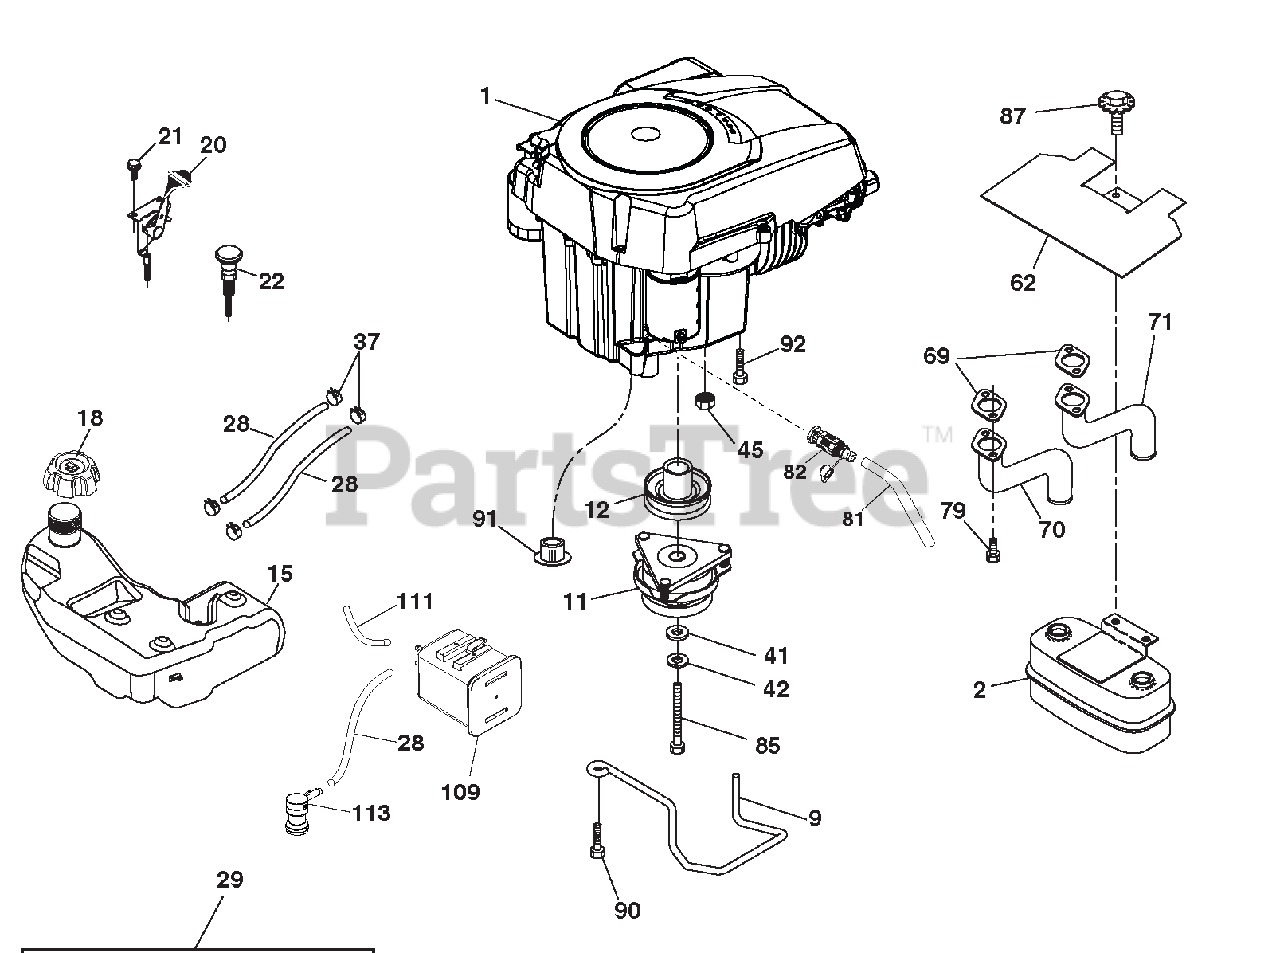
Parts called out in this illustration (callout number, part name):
1	(581497501) (ORDER PARTS FROM ENGINE
1	MANUFACTURER.)
2	MUFFLER ASM.TWIN.LO-TONE
9	KEEPER.BELT.ENGINE.4.25"NSTG
11	ELECTRIC CLUTCH
12	PULLEY.ENGINE.TUFFTORQE.1"CRK.
15	TANK.FUEL.ASM.3.00 GA.
18	CAP FUEL
20	CONTROL.THROTTLE
22	CONTROL CHOKE
28	LINE.FUEL.64"REAR.EMIS.CA.LP
29	KIT.SPARK ARRESTOR(392390 B&S)
37	CLAMP.HOSE.BLK.
41	WASHER.1-1/2 ODX15/32 IDX.250
42	WASHER.LOCK.HVY HLCL.SPR.7/16
45	Nut, Keps Hex 1/4-20 unc
62	SHIELD.HEAT.MUFFLER.
70	PIPE.EXHAUST.LH.CV18/20
71	PIPE.EXHAUST.RH.CV18/20
79	SCREW.SOCKET HD.5/16-18 X .75
81	TUBE.DRAIN.OIL.EASY
82	VALVE OIL DRAIN
85	BOLT.HEX.7/16-20 X 3.75 X GR.
87	BOLT.5/16-18UNCX3/4 W/SEMS.BLK
90	SCREW.3/8-16X1.SMGML.TAP/R.BLK
91	BUSHING.1.375OD.HEYCO 2210
92	SCREW.3/8-16 X 1.SMGML.TAP/R
109	CANISTER.CARBON.FILTER ASM.TEX
111	PURGE.LINE.CARB
113	VALVE.SLANT.CARTIDGE
